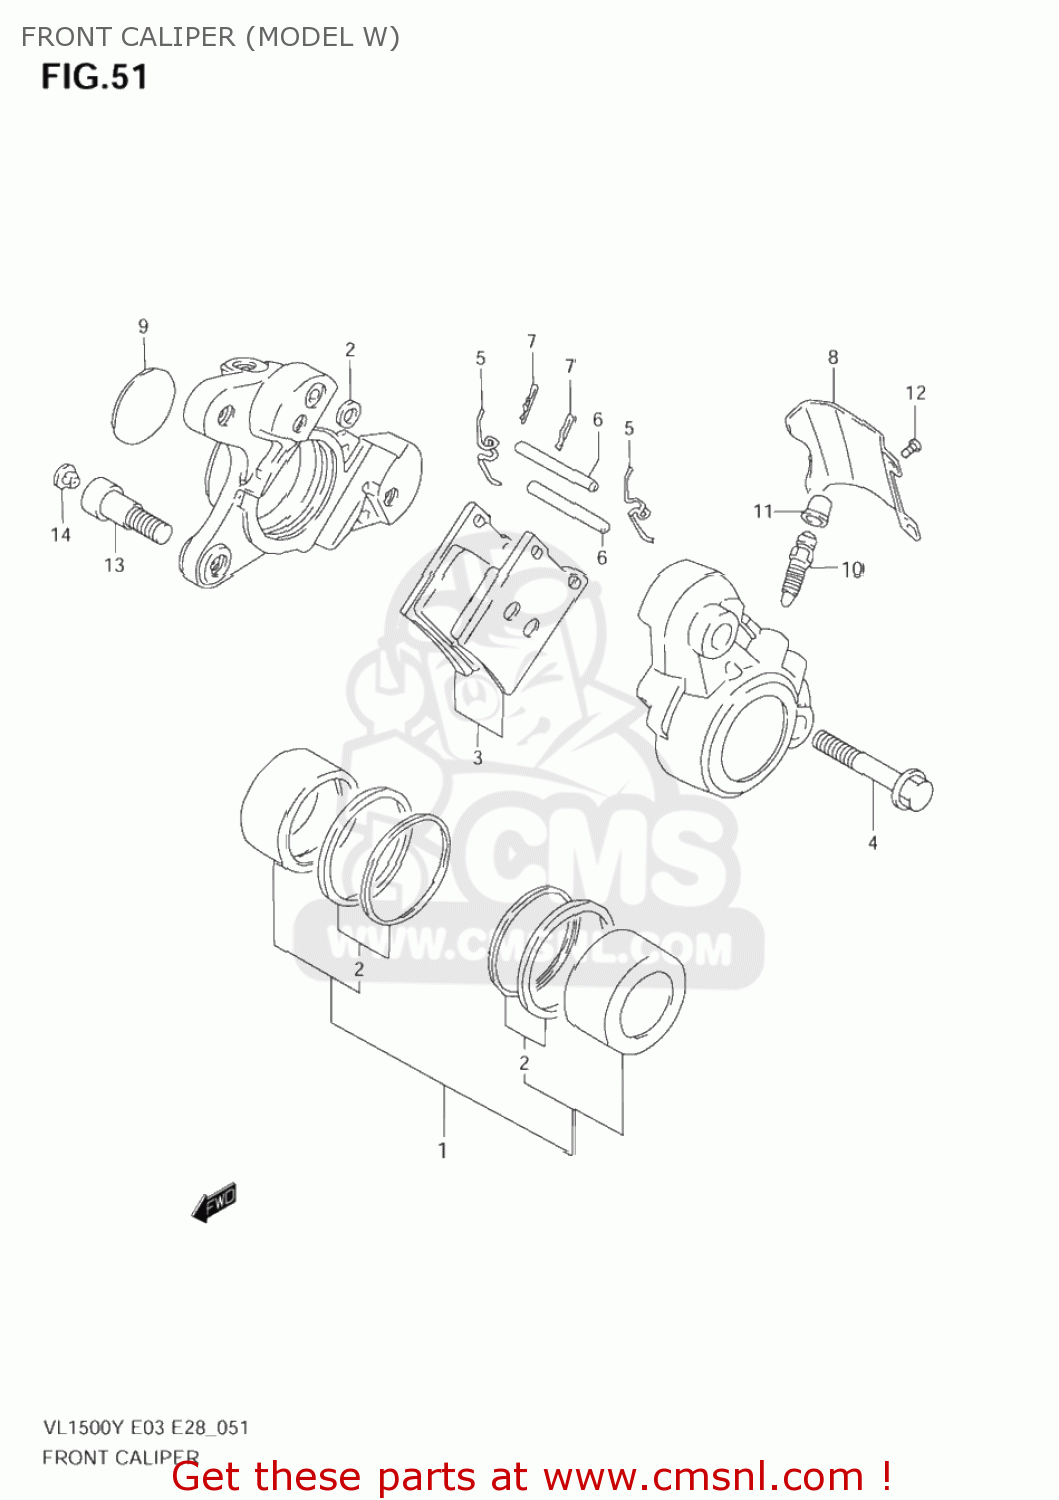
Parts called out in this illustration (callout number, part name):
1	PISTON SET
2	SEAL SET,PISTON
3	PAD SET (NAS)
4	BOLT,HOUSING
5	SPRING
6	PIN,PAD
7	CLIP,PAD PIN
8	COVER,CALIPER HOUSING,DUST
9	CAP,CALIPER
10	BLEEDER
11	CAP,BLEEDER PLUG
12	SCREW,CALIPER COVER(4X6)
13	BOLT(10X33)
14	CAP(OD:12)
